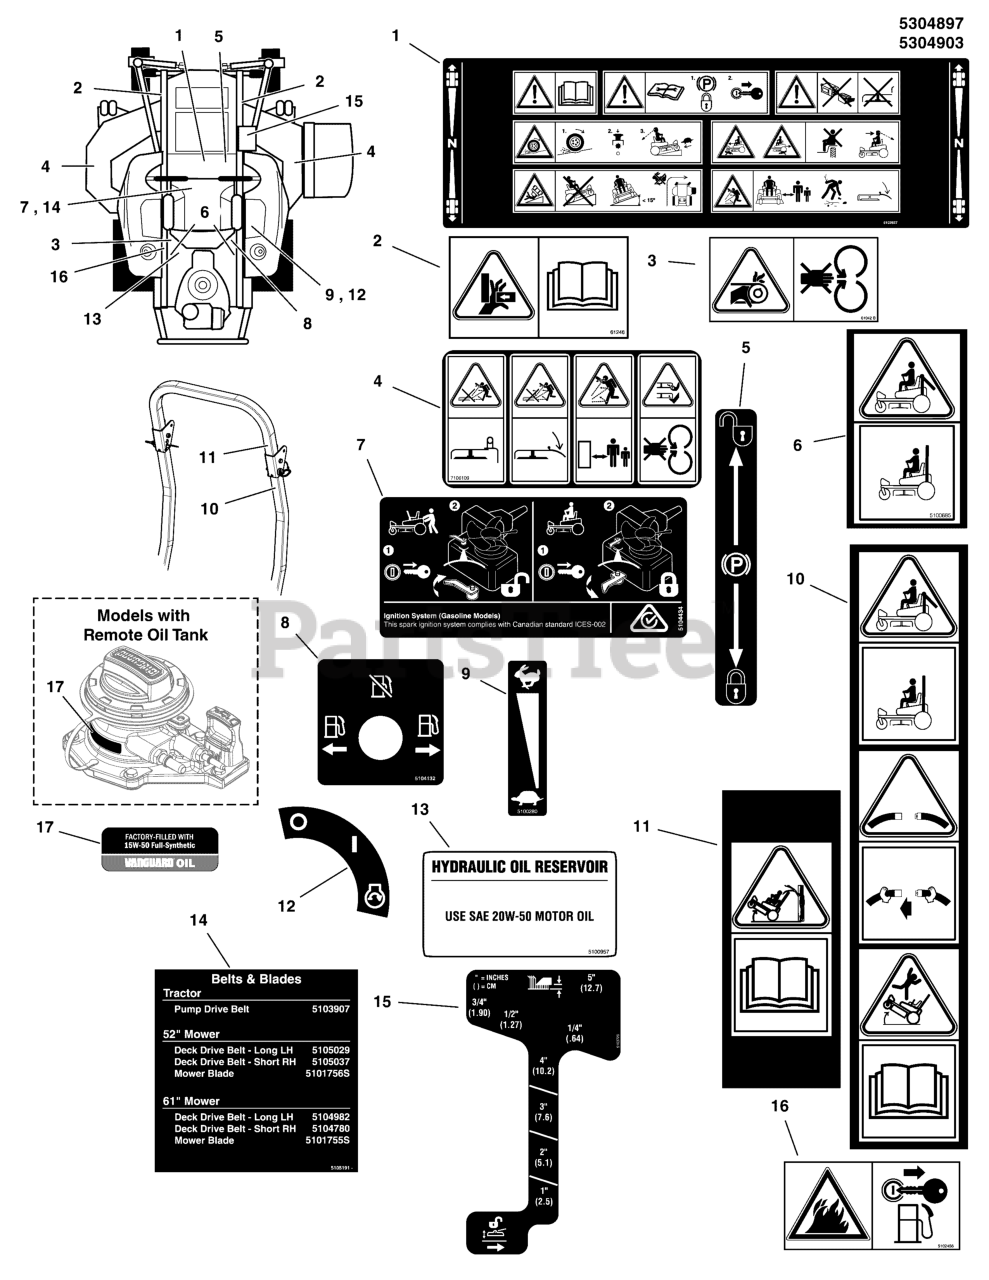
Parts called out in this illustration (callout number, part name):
1	DECAL, MAIN SAFETY, EXPORT
2	DECAL, PINCH POINT, CE
3	DECAL, CE DANGER
4	DECAL, DISCHARGE SAFETY, EXPORT
5	DECAL, PARKING BRAKE SYMBOLS
6	DECAL, WARNING, ROLLBAR, CE
7	DECAL, TRANSAXLE RELEASE, ZT440
8	DECAL, FUEL VALVE
9	DECAL, THROTTLE CONTROL
10	DECAL, SAFETY, CE ROPS
11	DECAL, SAFETY, CE ROPS, OBS
12	DECAL, IGNITION SWITCH
13	DECAL, HYDRAULIC OIL, SAE 20W50
14	DECAL, BELT & BLADE IS2100Z COBALT 2BELT
15	DECAL, CUTTING HEIGHT
16	DECAL, FIRE ANSI EXPORT
17	LABEL, OIL INFORMATION
